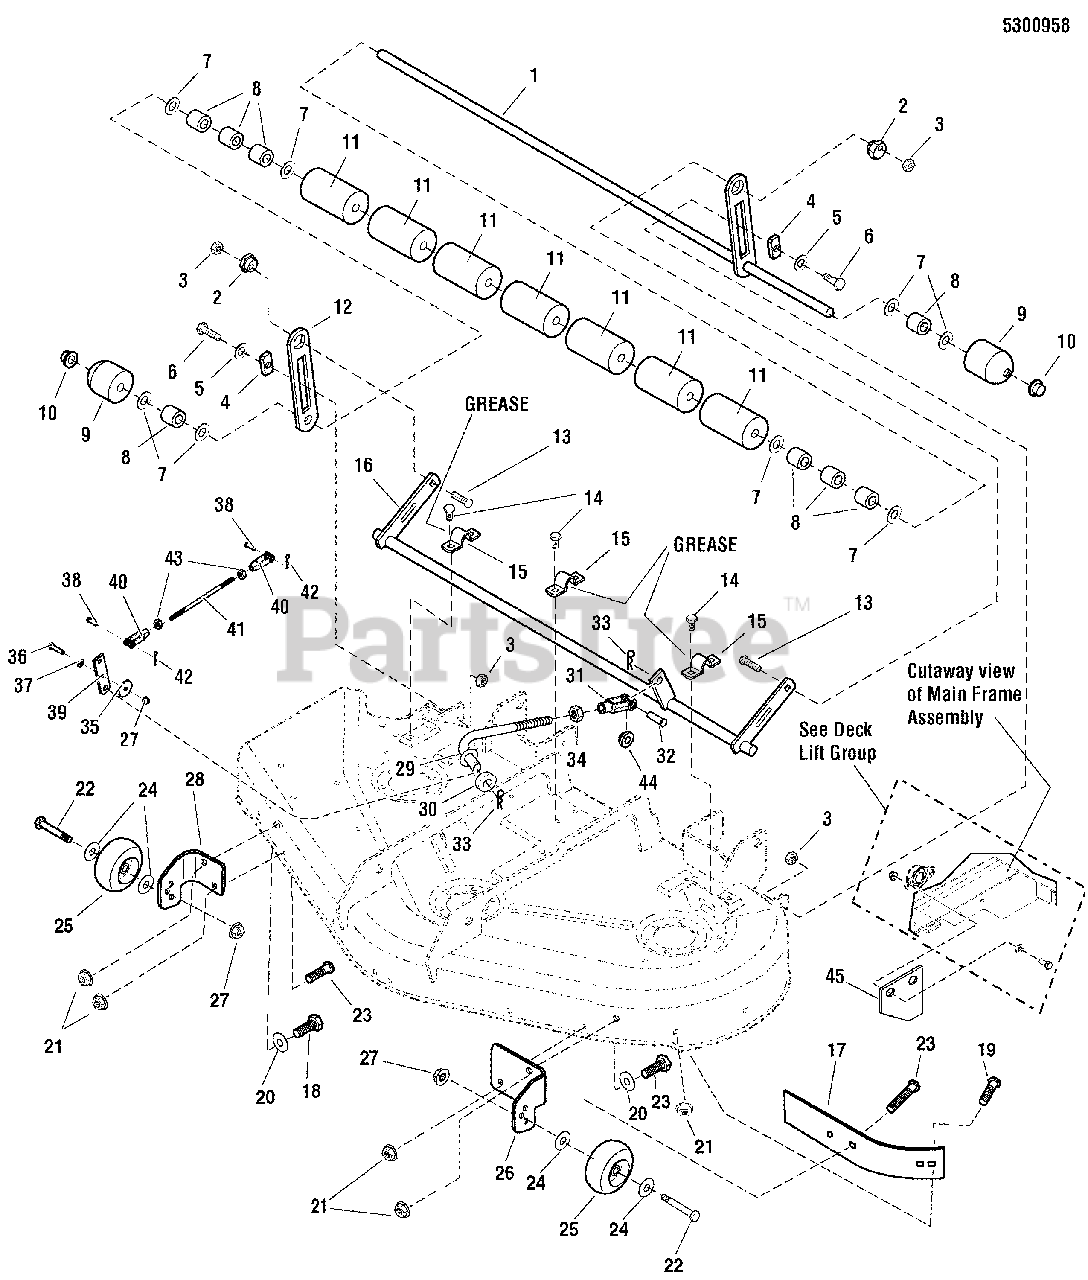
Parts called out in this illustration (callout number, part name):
1	WELD,SHAFT,ROLLER,44
2	NUT, Hex Adjusting, .99 DIA .687
3	NUT-HEX TOPLOCK SPIRAL FLNG 3/8-16 YEL
4	SLIDE .803 X 1.7
5	WASHER-0500(0.53IDX1.25X.08THK)BLK
6	BOLT, Shoulder, 3/8-16 X 1.34
7	WASHER, 5/8
8	SPACER, .66 ID
9	ROLLER,ROUNDED
10	NUT-PUSH FOR .625 DIA STUD CAPPED BLK
11	ROLLER-0.652ID 2.50 OD 4.10LG BLACK POLY
12	BAR, ROLLER
13	BOLT-RD HD SH SQ NK 3/8-16X1.500 G5 BLK
14	SCREW-HEX WSHR HD TAPTT5/16-18X0.750BLK
15	STRAP-1.00WD 3.06LG .134THK ROLLER ECOAT
16	WELD,SHAFT,DECK LIFT,44
17	SHORT BLOWOUT BAFFLE BLACK
18	BOLT, 5/16-18 X 1, CARRIAGE
19	BOLT, 5/16-18 X 3/4", CARRIAGE
20	WASHER, 5/16 SAE
21	NUT, 5/16-18 HEX NYLOCK FLANGE
22	BOLT-WHEEL 3/8-16X2.781 .750 THRD YELLOW
23	BOLT, 5/16-18 X 1 GD5 YZ
24	WASHER-0500(0.51IDX0.87ODX.06THK) BLK
25	WHEEL- 2.00 WIDE 3.92 DIA 0.531ID POLY
26	BRACKET, GAUGE WHEEL, LH
27	NUT, 3/8-16 HEX NYLOCK FLANGE
28	BRACKET, GAUGE WHEEL, RH
29	ROD, DECK LIFT
30	SPACER, HYDRO PULLEY
31	CLEVIS, 1/2-20, STEEL
32	PIN, CLEVIS, 1/2 X 1 1/2, YZP
33	PIN, HAIR, .0915 X 1-7/8
34	NUT, 1/2-20 HEX JAM
35	WASHER, .41 X 1.75 X .14
36	BOLT, 3/8-16 X 1-1/2 GD5 YZ
37	WASHER, 3/8 SAE
38	PIN, CLEVIS, 3/8 X 1
39	LINK, ROLLER REVERSE
40	CLEVIS 3/8-24, PLASTIC
41	ROD, LEVER CONNECTING
42	PIN, COTTER, 3/32" X 3/4
43	NUT, 3/8-24 HEX JAM
44	BUSHING, DECK SUPPORT
45	PLATE, DECK STOP
